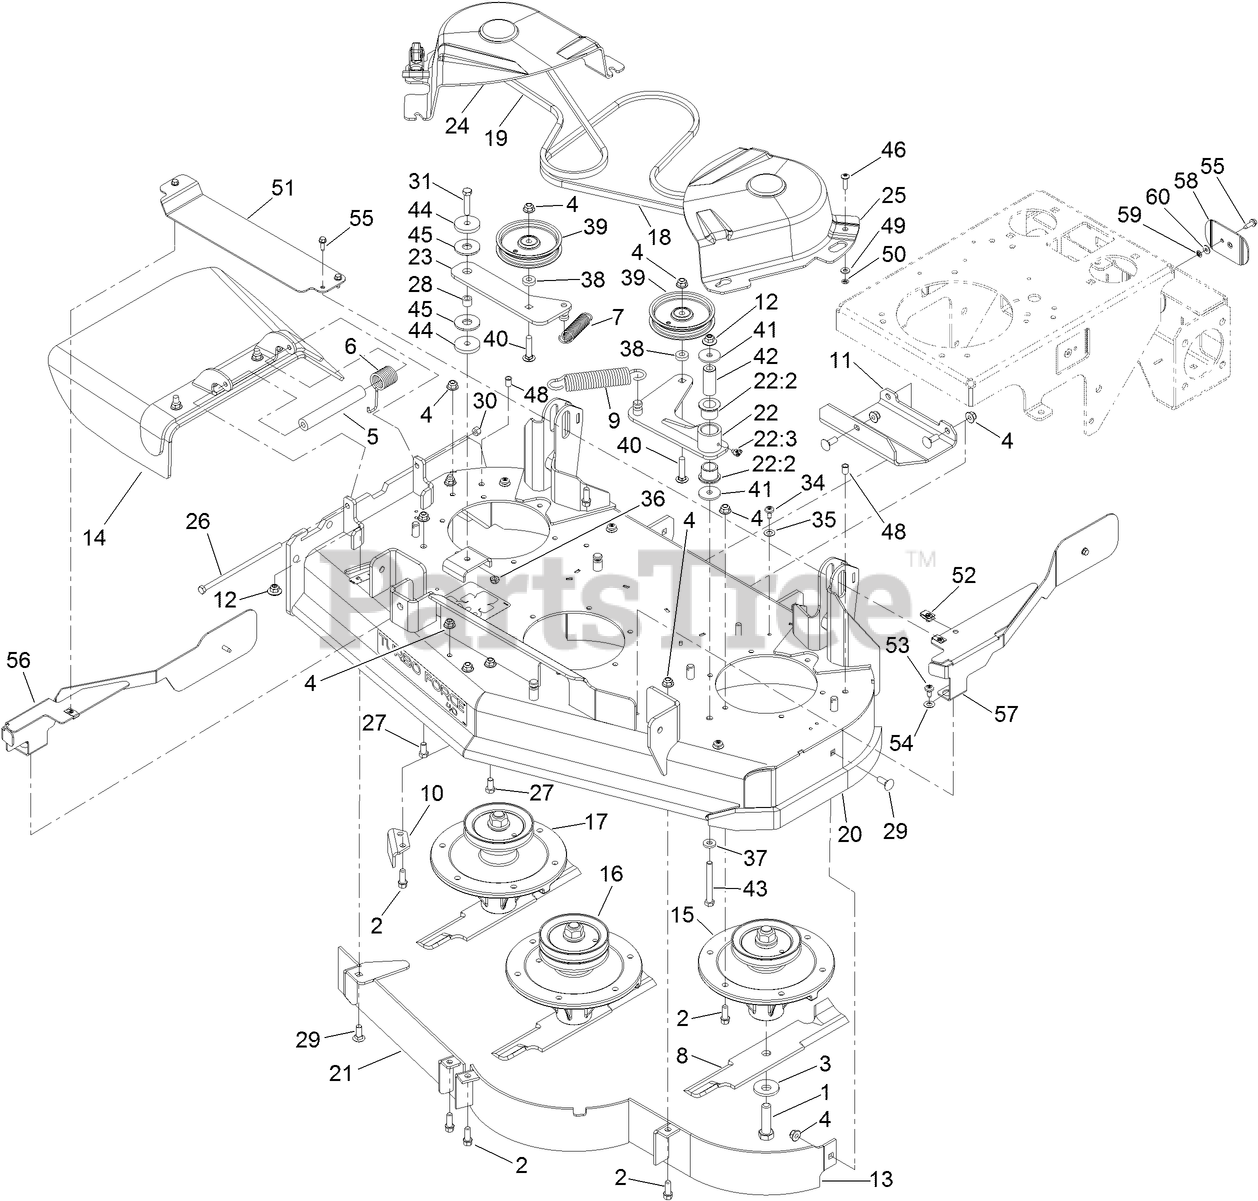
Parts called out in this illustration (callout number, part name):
1	SCREW-BLADE
3	WASHER-BLADE BOLT, HEAVY
4	NUT-HF, NI
5	SPACER
6	SPRING-TORSION
7	SPRING-EXTENSION
8	BLADE-14 INCH (HIGH SAIL)
9	SPRING-EXTENSION
10	BAFFLE-DISCHARGE
11	PLATE-SKID
12	NUT-FLANGE, NI
13	BAFFLE ASM
14	DEFLECTOR ASM
15	SPINDLE ASM
16	SPINDLE ASM
17	SPINDLE ASM
18	BELT-V
19	BELT-V
20	DECK AND DECAL ASM
21	FRONT BAFFLE ASM
22	IDLER ARM ASM
22:2	BUSHING
22:3	FITTING-LUBE, 45 DEG
23	IDLER ARM ASM
24	COVER-BELT, RH
25	COVER-BELT, LH
26	SCREW-HH
27	SCREW-HH
28	BUSHING-LEVER, LIFT
29	BOLT-CARR
30	NUT-LOCK, NI
31	SCREW-HH
34	SCREW-SHOULDER
35	WASHER-THRUST
37	SPACER
38	SPACER
39	PULLEY-IDLER
40	SCREW-CARR
41	WASHER
42	SPACER-PLAIN
43	SCREW-HH
44	WASHER-PLAIN
45	WASHER-FRICTION, COMPOSITE
46	SCREW-TTH
48	NUT-CLINCH
49	WASHER-FLAT
50	NUT-RETAINER
51	GUARD-DECK, CENTER
53	SCREW-SHOULDER
54	WASHER-THRUST
55	SCREW-HWH, THREAD ROLL
56	GUARD-DECK, RH
57	GUARD-DECK, LH
58	GUARD-PLATE
59	NUT-RETAINER
60	WASHER
